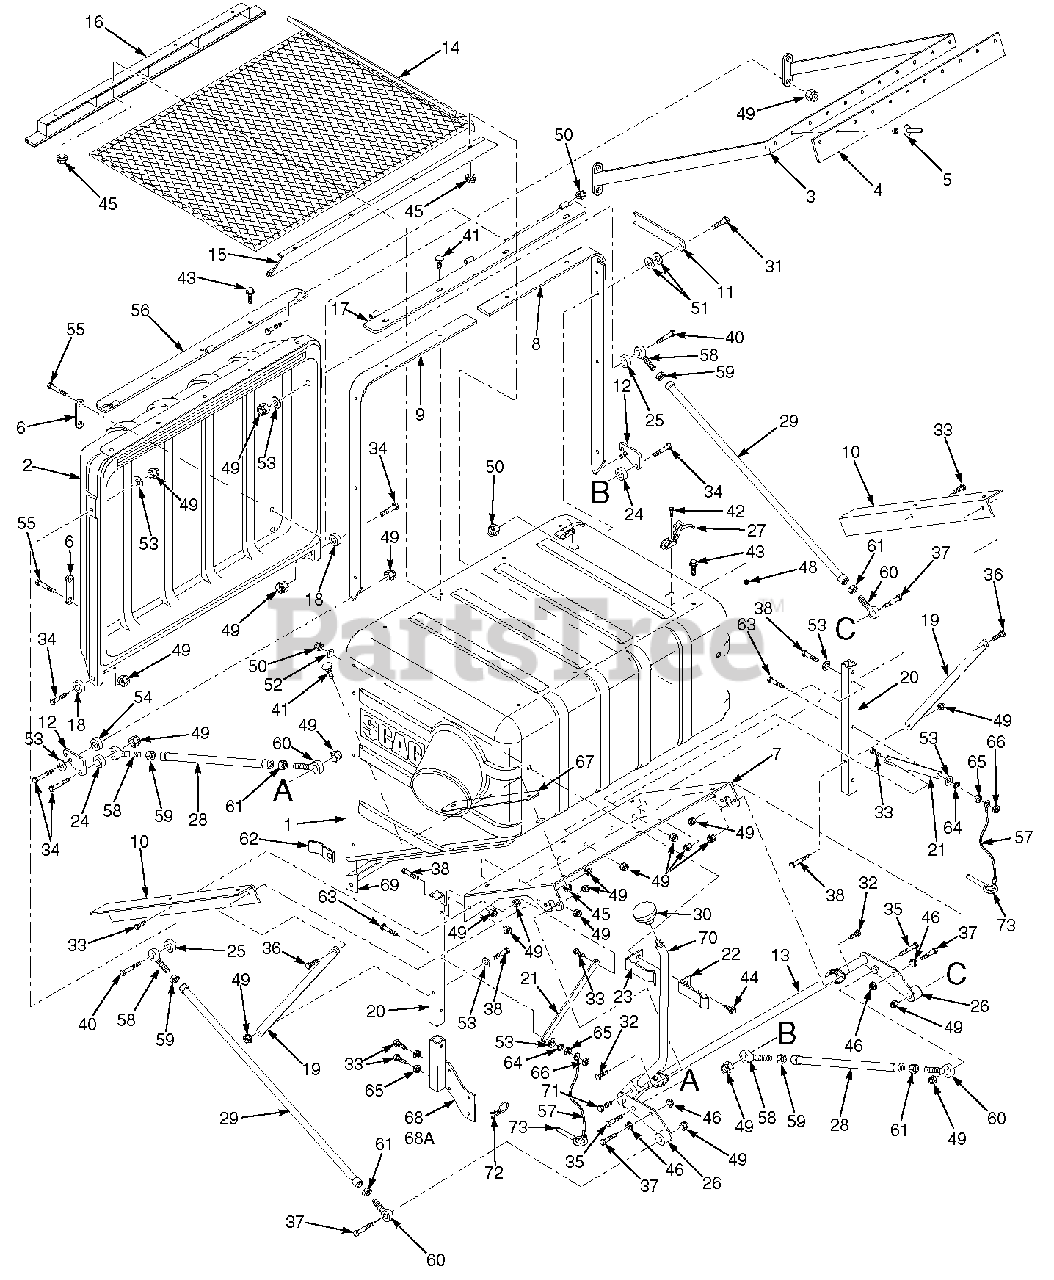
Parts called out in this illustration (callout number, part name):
1	Hopper, GC-STC-CS
2	Door, GC-CS
3	Sweeper Weldment, GC-CS
4	Pad, Rubber
5	Pop Rivet, 3/16 x .652
6	Plate, Stiffener
7	Support Frame, Hopper
8	Hinge Bracket, LH
9	Hinge Bracket, RH
10	Bracket, Hopper Support
11	Latch, Door Prop
12	Plate, Latch
13	Bellcrank Weldment, Upper
14	Debris Screen Weldment
15	Screen Support Weldment, Rear
16	Screen Support Weldment, Front
17	Hinge Weldment, Hopper
18	Spacer
19	Brace Stiffener, Short
20	Tube, Upright
21	Brace, Engine Mount
22	Latch, Dump Rod Inner
23	Latch, Dump Rod Outer
24	Spacer
25	Spacer
26	Spacer
27	Latch, Hood
28	Linkage Assembly, Lower
29	Linkage Assembly, Upper
31	Bolt, Hex Head 5/16-18 x 1-1/4"
32	Bolt, Hex Head 3/8-16 x 3/4"
33	Bolt, Hex Head 3/8-16 x 1"
34	Bolt, Hex Head 3/8-16 x 1-1/2"
35	Bolt, Hex Head 3/8-16 x 1-3/4"
36	Bolt, Hex Head 3/8-16 x 1-1/4"
37	Bolt, Hex Head 3/8-16 x 2"
38	Bolt, Hex Head 3/8-16 x 2-1/4"
39	Bolt, Hex Head 5/16-18 x 3-1/2"
40	Bolt, Hex Head 3/8-16 x 3-1/2"
41	Bolt, Carriage 5/16-18 x 1"
42	Screw, #10-32 x 1/2"
43	Cap Screw, 5/16-18 x 3/4" Serr. Flan.
44	Cap Screw, 5/16-18 x 1" Serr. Flan.
45	Nut, 5/16-18 Serrated Flange
46	Nut, 3/8-16 Serrated Flange
47	Nut, 3/8-16 UNC Jam
48	Nut, #10-32 Elastic Stop
49	Nut, 3/8-16 Elastic Stop
50	Nut, 5/16-18 Elastic Stop
51	Washer, Special Wave
52	Washer, 5/16-.375 x .875 x .083 Flat
53	Washer, 3/8-.931 x .938 x .105 Flat
54	Bushing, Hopper Latch GC-CS
55	Bolt, Hex Head 3/8-16 x 3"
56	Hinge Weldment, Door
57	Lanyard
58	Rod End Male, 3/8-24 LH Thread
59	Nut, 3/8-24 UNF L.H. Thread
60	Rod End Male, 3/8-24 RH Thread
61	Nut, 3/8-24 UNF R.H. Thread
62	Alignment Bracket, GC-CS
63	Bolt, Hex Head 3/8-16 x 2-1/2"
64	Lock Wasker, 3/8-16 Spring
65	Nut, 3/8-16 UNC Zinc
66	Nut, 3/8-16 Center Lock
67	Retainer Strip, Hopper
68	Mounting Bracket Weldment, RH
68A	Mounting Bracket Weldment, LH
69	Bracket, Lower Stiffener
70	Rod, Dump Lever
71	Bolt, Hex Head 5/16-18 x 1-3/4"
72	Hair Pin, Cotter
73	Pin, Ring 1/2" x 2-1/4"
